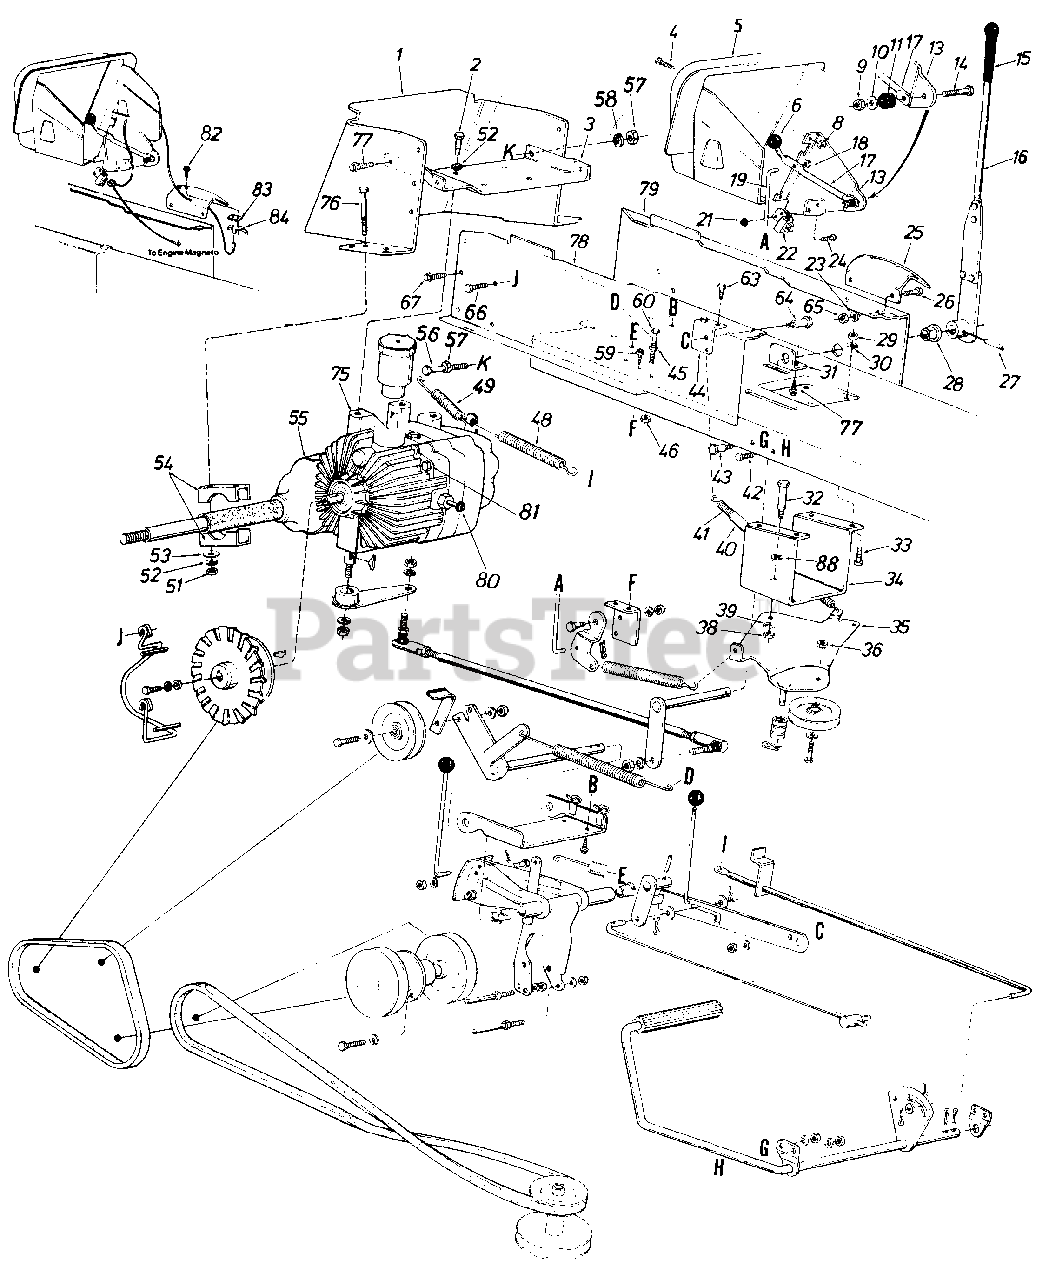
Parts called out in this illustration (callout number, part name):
1	Hitch Plate
2	Hex Bolt 3/8-16 x .75" Lg.
3	Rear Axle Support Brkt.
4	Truss Mach. Scr. 1/4-20 x .50" Lg.
5	Dash Panel Ass'y.
6	Knob-Blade Clutch
8	Hex Sems Nut 1/4-20 Thd.
9	Hex Cent. L-Nut 1/4-20 Thd.
10	Fl-Wash. .28" I.D. x .74" O.D. x.063
11	Rubber Wash. .33" I.D. x .87" O.D. x .30
13	Deck Clutch Cont. Brkt.
14	Hex Bolt 1/4-20 x 1.25" Lg.
16	Control Arm Ass'y.
17	Blade Clutch Lever
18	Push Nut 1/4" O.D. Rod
19	Deck Control Rod
21	Hex Nut #10-24 Thd.
22	Safety Switch
23	L-Wash. 5/16" I.D.
24	Truss Mach. Scr. #10-24 x .50" Lg.
25	Speed Control Bracket
26	Hex Bolt 5/16-18 x .62" Lg.
27	Spring Pin Spiral 1/4" Dia. x 1.5" Lg.
28	Hex Flange Brg.
29	Hex Nut 5/16-18 Thd.
30	L-Wash. 5/16" I.D.
31	Speed Control Shaft Brkt.
32	Shld. Scr. .437" Dia. x .162" Lg.
33	Hex Bolt 5/16-18 x 1.00" Lg.
34	Idler Support Brkt.
35	Idler Brkt. Ass'y.
36	Hex L-Nut 3/8-16 Thd.
38	Hex Nut 5/16-18 Thd.
39	L-Wash. 5/16" I.D.
40	Convoluted Conduit .50" I.D.
41	Ext. Spring .50" O.D. x 6.37" Lg.
42	Hex Bolt 3/8-16 x .62" Lg.
43	Shld. Scr. .50" Dia. x .395"Lg. (3/8-16)
44	Parking Brake Cam Mtg. Brkt.
45	Hex Nut 5/16-28 Thd.
46	Hex L-Nut 5/16-18 Thd.
48	Brake Tension Spring
49	Ext. Spring-Brake Return
51	Hex Nut 3/8-16 Thd.
52	L-Wash. 3/8" I.D.
53	Fl-Wash. .390" I.D. x 1.00" O.D. x .125" Thk.
54	Rear Axle Bracket
55	Transaxle
56	Hex Bolt t/4-20 x 2" Lg.
57	Hex Nut 1/4-20 Thd.
58	L-Wash. 1/4" I.D.
59	Hex Wash. Hd. Self-Tap Scr. 1/4-20 x .50" Lg.
60	Hex Bolt 5/16-18 x 1.50" Lg.
63	Hex Wash. Hd. Self-Tap Scr. 1/4-20 x .50" Lg.
64	Shld. Scr. .437" Dia. x .162" Lg.
65	Hex Nut 5/16-18 Thd.
66	Hex Wash. Hd. Scr. 3/8-16 x .50" Lg.
67	Hex Wash. Hd. Self-Tap Scr.5/16-18 x 75n Lg.
75	Hydrostatic Pump Comp.
76	Hex Bolt 3/8-16 x 3.5" Lg.
77	Hex AB-Tap Scr. 5/16 x.75" Lg.
78	Side Panel Upper Frame R.H.
79	Side Panel Upper Frame L.H.
81	Socket Hd. Bolt 3/8-16 x 2.75" Lg.
82	Hex Wash. Hd. Scr. #8 x .50" Lg.
83	Insulator Nut Plate
84	Spring Switch
88	Wave Washer
